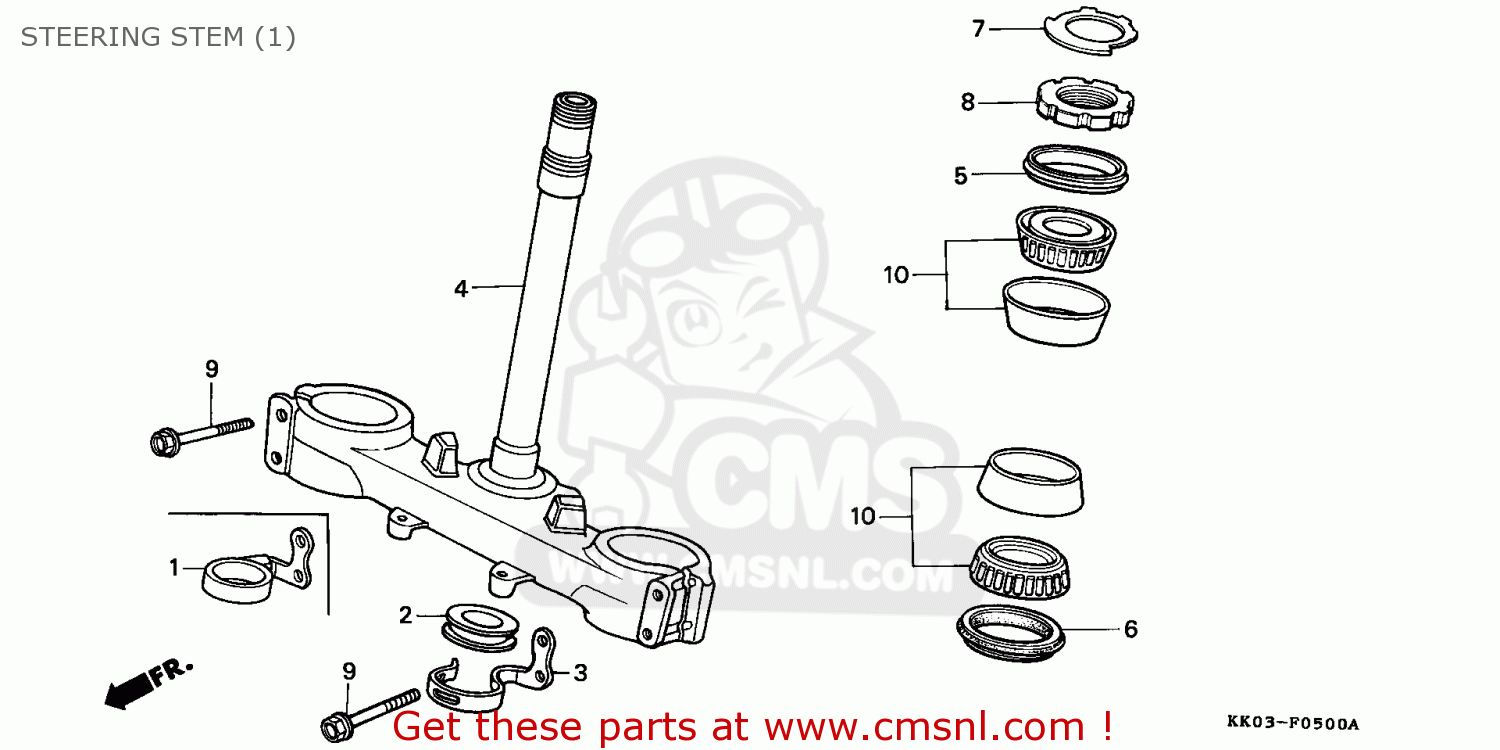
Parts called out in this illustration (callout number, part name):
2	INN,CABLE GUIDE
3	GUIDE,BRK.CABLE
4	STEM COMP.,STEERI
5	DUST SEAL,STRG.
6	DUST SEAL,STRG.HD
7	WASHER,TOP THREAD
8	THREAD,STEERING H
9	BOLT,FLANGE,DR,8X
10	R/BRG TAP N/COM
